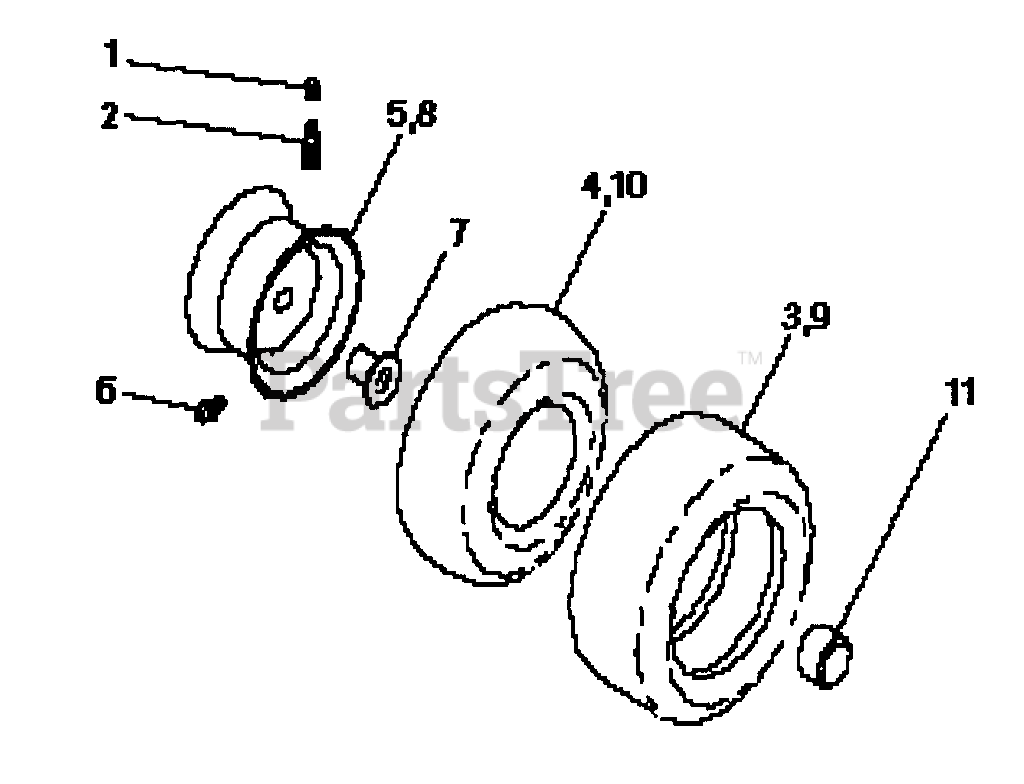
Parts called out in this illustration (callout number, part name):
1	Cap Valve Tire
2	Stem Valve
3	Tire F Ts 15 X 6 0 - 6 Service
4	Tube Front
5	Rim Asm 6" front Service
6	Fitting Grease
7	Bearing Flange
8	Rim Asm 8" rear Service
9	Tire R Ts 18x9 5-8 C Service
10	Tube Rear
11	Cap Axle Blk 1 50 X 1 00
